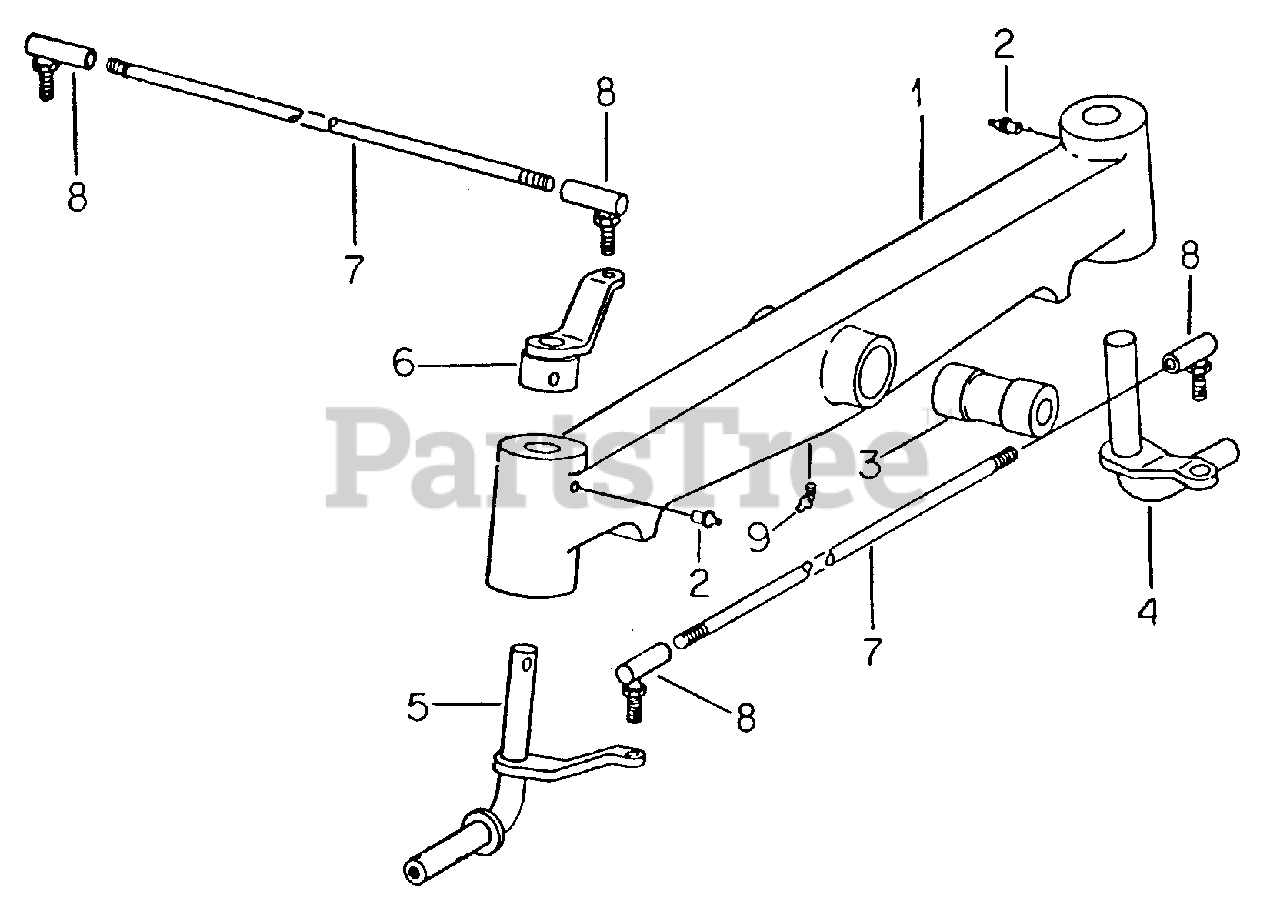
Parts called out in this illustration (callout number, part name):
1	Axle, Front
2	Fitting, 3/16 Drive Type Str Lube
3	Bushing, Axle Pivot
4	Knuckle Assy, LH
5	Knuckle Assy, RH
7	Link, Drag
8	Joint Assy, Drag Link Ball
9	Fitting, 3/16 45 Deg Angle Drive Type
